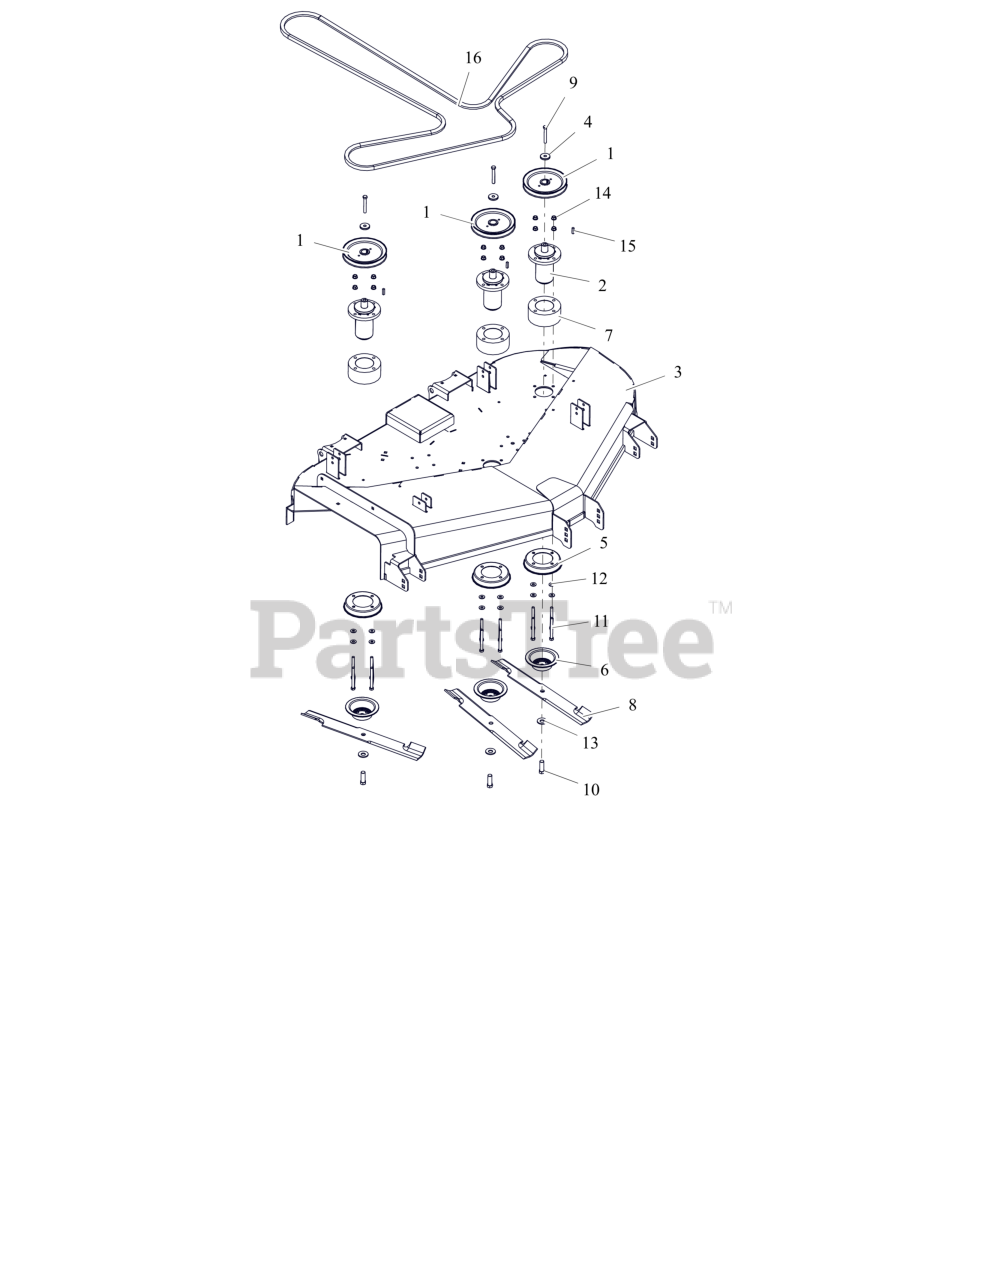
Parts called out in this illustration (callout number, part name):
1	PULLEY, V-1" ID X 6.75 OD
2	ASM, MAINT FREE ALUM SPINDLE
3	WLDMT, TUNNEL DECK
4	RETAINER, SHEAVE
5	GUARD, SPINDLE TOP
6	GUARD, SPINDLE DEBRIS
7	SPCR, SPINDLE
8	BLADE, MOWER 20.940 X 1.00 LIFT
9	BLT, HEX .38-16X2.75 G8 ZCC
10	BLT, HEX .62-18X1.75 G8 ZCC
11	BLT, HEX 0.375-16X3.75 GR8 ZCC
12	WSHR,FLT .375X.875X.083 ZCC
13	WSHR-BLVL .669X1.535X.138
14	NUT-LK-CTR-FLG .375-16 GF ZCC
15	KEY, SQ .25X.25X1.00 RC 40-50
16	V-BELT, HB SECTION
